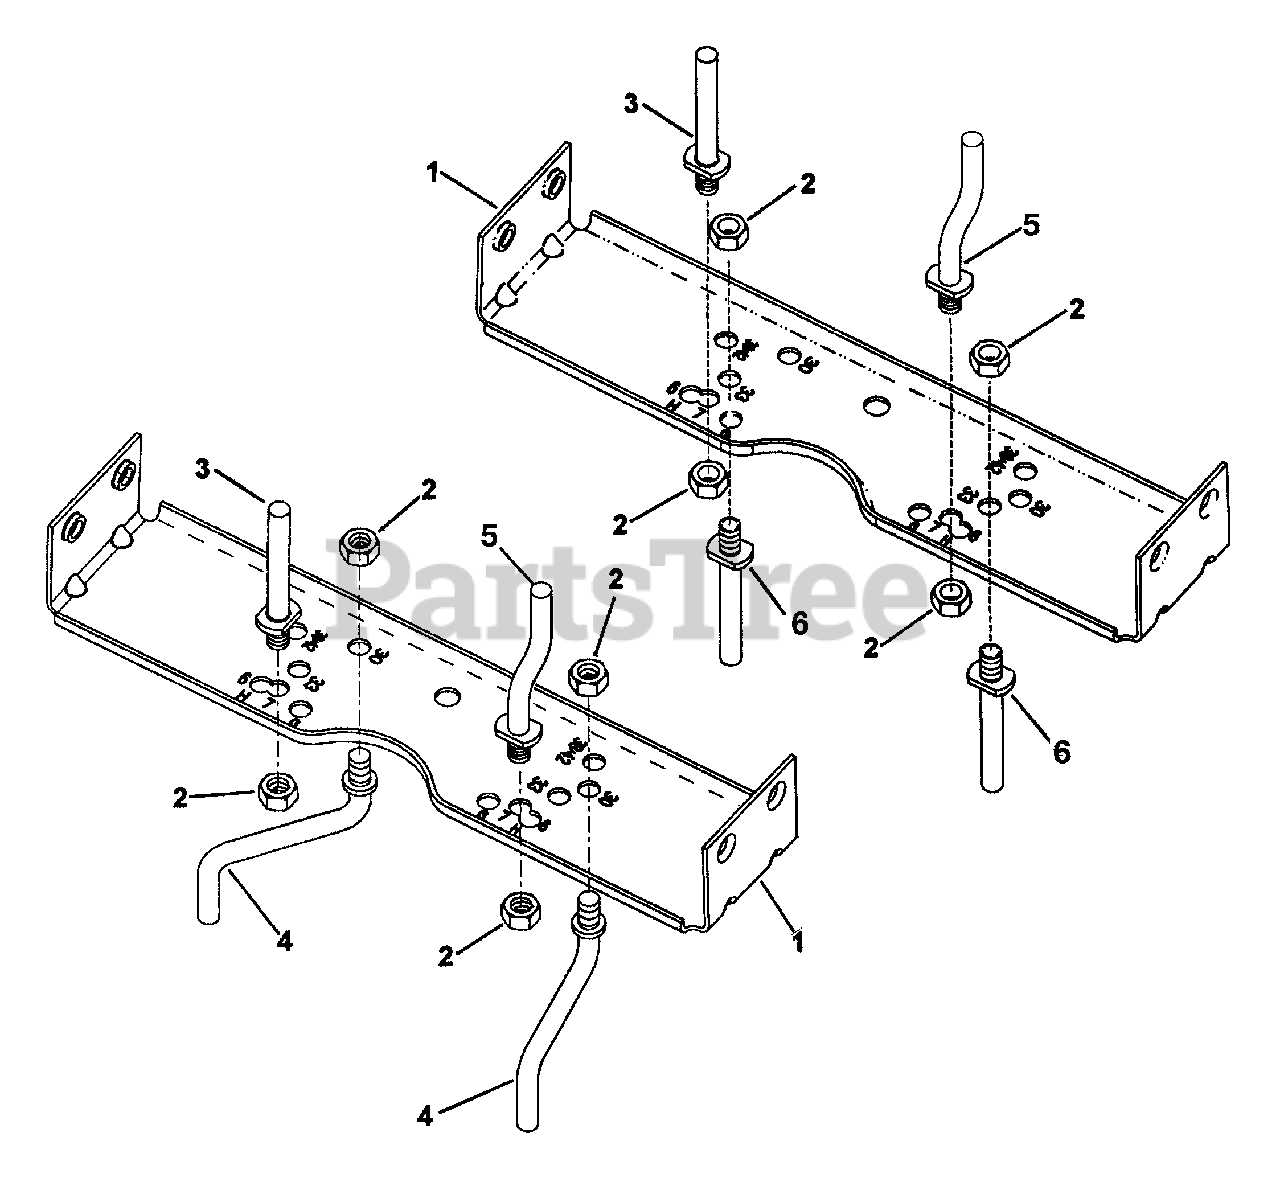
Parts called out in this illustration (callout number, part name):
1	BRACKET, Belt Guide
2	NUT, 5/16-18 Hex Center Lock, Grade B or 5
3	STUD, Belt Guide
4	STUD, Belt Guide 38" Dual Brake Deck
5	STUD, Belt Guide
6	STUD, Belt Guide 33" Deck
